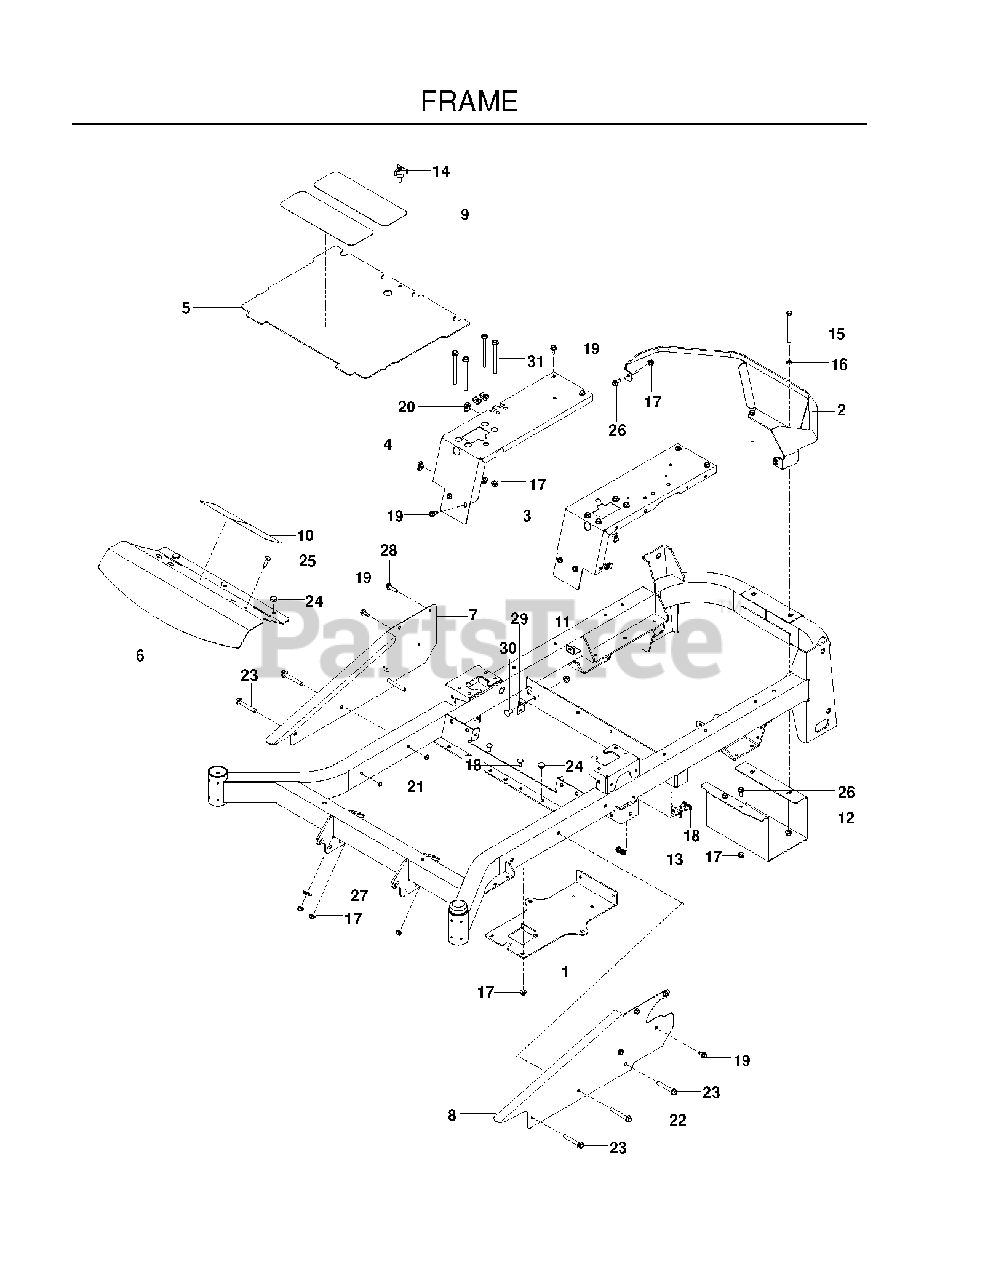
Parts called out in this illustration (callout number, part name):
1	PLATE, BATTERY, BLACK
2	GUARD, REAR MZ, GRAY
3	PANEL, FILLER LT, ORG
4	PANEL.FILLER.RT.ORNAGE
5	PLATE, FLOOR W/DECALS
6	PLATE, FOOTREST
7	SIDE.RT.ORANGE
8	SIDE.LT.ORANGE
9	ANTI-SKID PAD
11	NUT 3/8-16 HEX FLG NYLOC ZD
12	SHIELD.MUFFLER.BLACK
13	STOP, DECK, EZ+
14	KNOB W/STUD
15	HCS 5/16C X 4
16	FLAT WASHER 5/16 SAE
17	5/16-18 NYLOC FLANGE NUT
18	BOLT 5/16C X 3/4" CARRIAGE
19	BOLT 5/16-18 X 3/4
20	U-CLIP 5/16-18 NUT RETAINER
21	NUT HEX 3/8-16 NYLON, THIN
22	HHFS 3/8-16 X 2 3/4
23	HHFS 3/8-16 X 2.5 GR 5 ZD
24	GROMMET, BUMPER
25	RHSNB 5/16C X 1
26	HHFS 5/16-18 X 3/4
27	WASHER 1/2" FLAT
28	HHFS 5/16-18 X 1.25 TPBLT GD 5
29	BRACKET.DAMPENER.BLACK
30	RHSNB 3/8-16 X 3/4 GR 5 BLK ZN
31	HHFS 5/16-18 X 3 3/4
